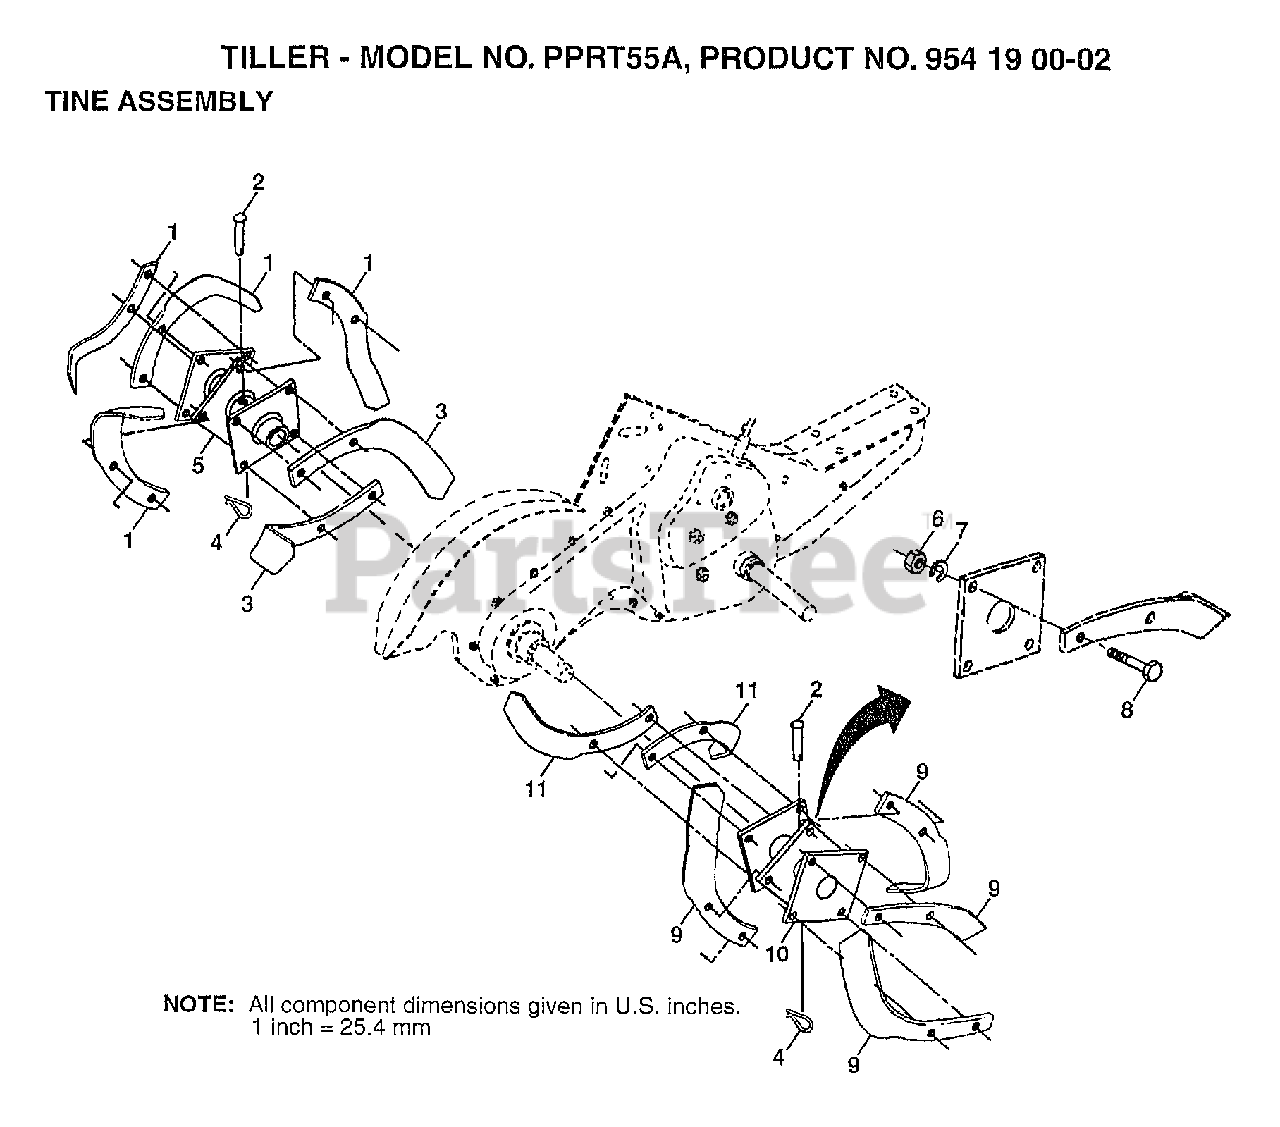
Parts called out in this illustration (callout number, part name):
2	PIN.CLEVIS.SHEAR
3	"TINE.LH.12"""
4	CLIP HAIRPIN
5	HUB&PLATE ASM LH
7	LOCKWASHER
8	BOLT
10	HUB&PLATE ASM RH
11	"TINE.RH.12"""
